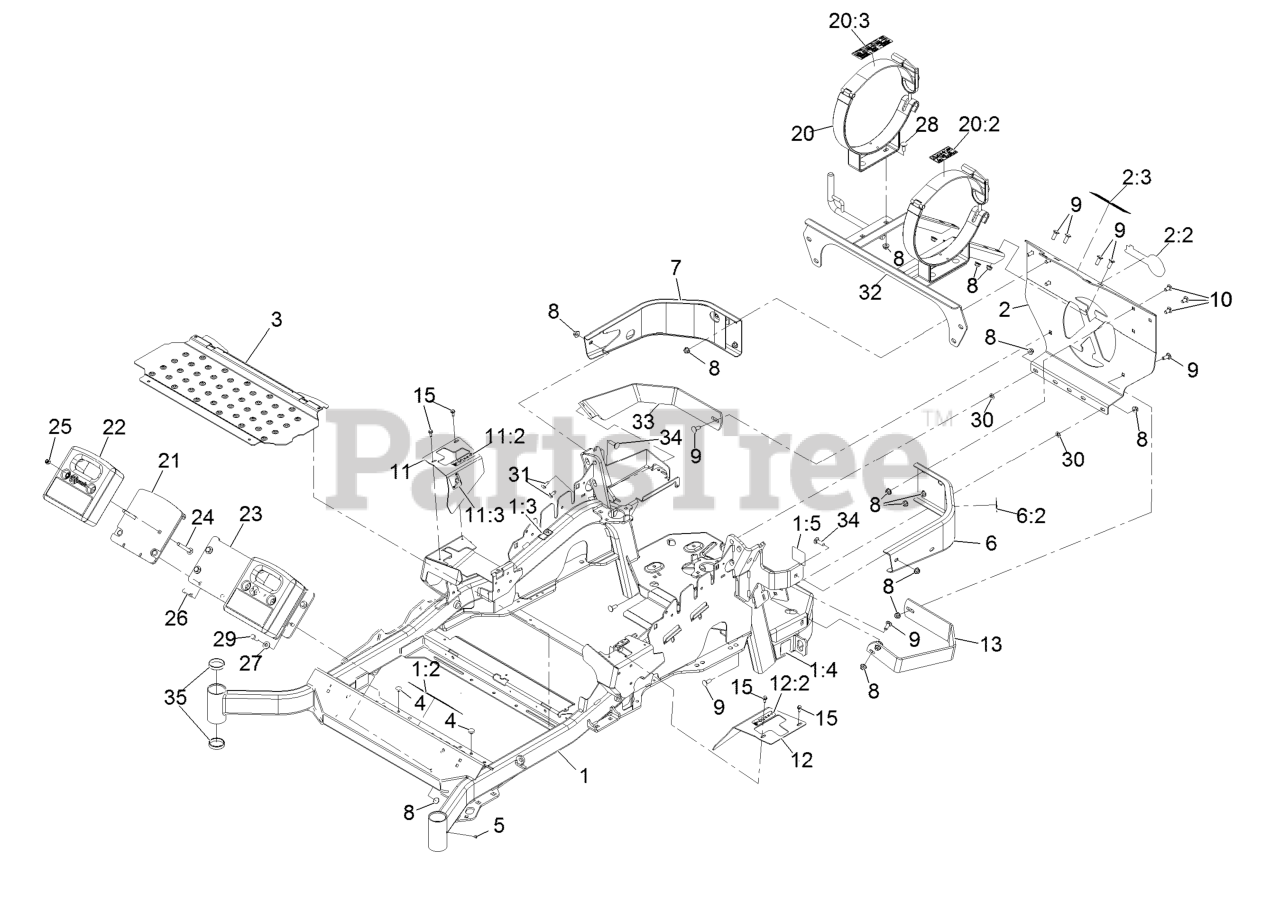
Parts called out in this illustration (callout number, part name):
1	Mainframe ASM
1:2	Decal-Danger
1:3	Decal-Warning
1:4	Decal-Hazard, Finger
1:5	Decal-Spark Arrester
2	Rear Guard-LP W/Decals
2:2	Decal-Exmark Logo
2:3	Decal-LPG Fuel Tank Replacement
6	LH Bumper ASM
6:2	Decal-Warning
7	Bumper-RH
8	Nut-HF, NI
9	Screw-CARR
10	Screw-CARR
11	RH Motion Control Cover ASM
11:2	Decal-Control, Motion
11:3	Decal-Park Brake, CE
12	LH Motion Control Cover ASM
12:2	Decal-Control, Motion
13	Guard-Muffler
15	Screw-HWH
20	Tank Bracket ASM (Set)
20:2	Decal-LPG Warning
20:3	Decal-LPG Tank Spec
21	Asm, Weight W/Decals
22	Weight,Cast 36Lb
23	Plate, Weight Mounting
24	Screw-CARR
25	Nut-Lock, NI
26	Pin-Hair
27	Washer-Belleville
28	Bolt-CARR
29	Screw-HH
30	Nut-Push
31	Screw-HWHTF
32	Support-LPG Tank
33	Strap-Guard
34	Bolt-CARR
35	Cup-Bearing
